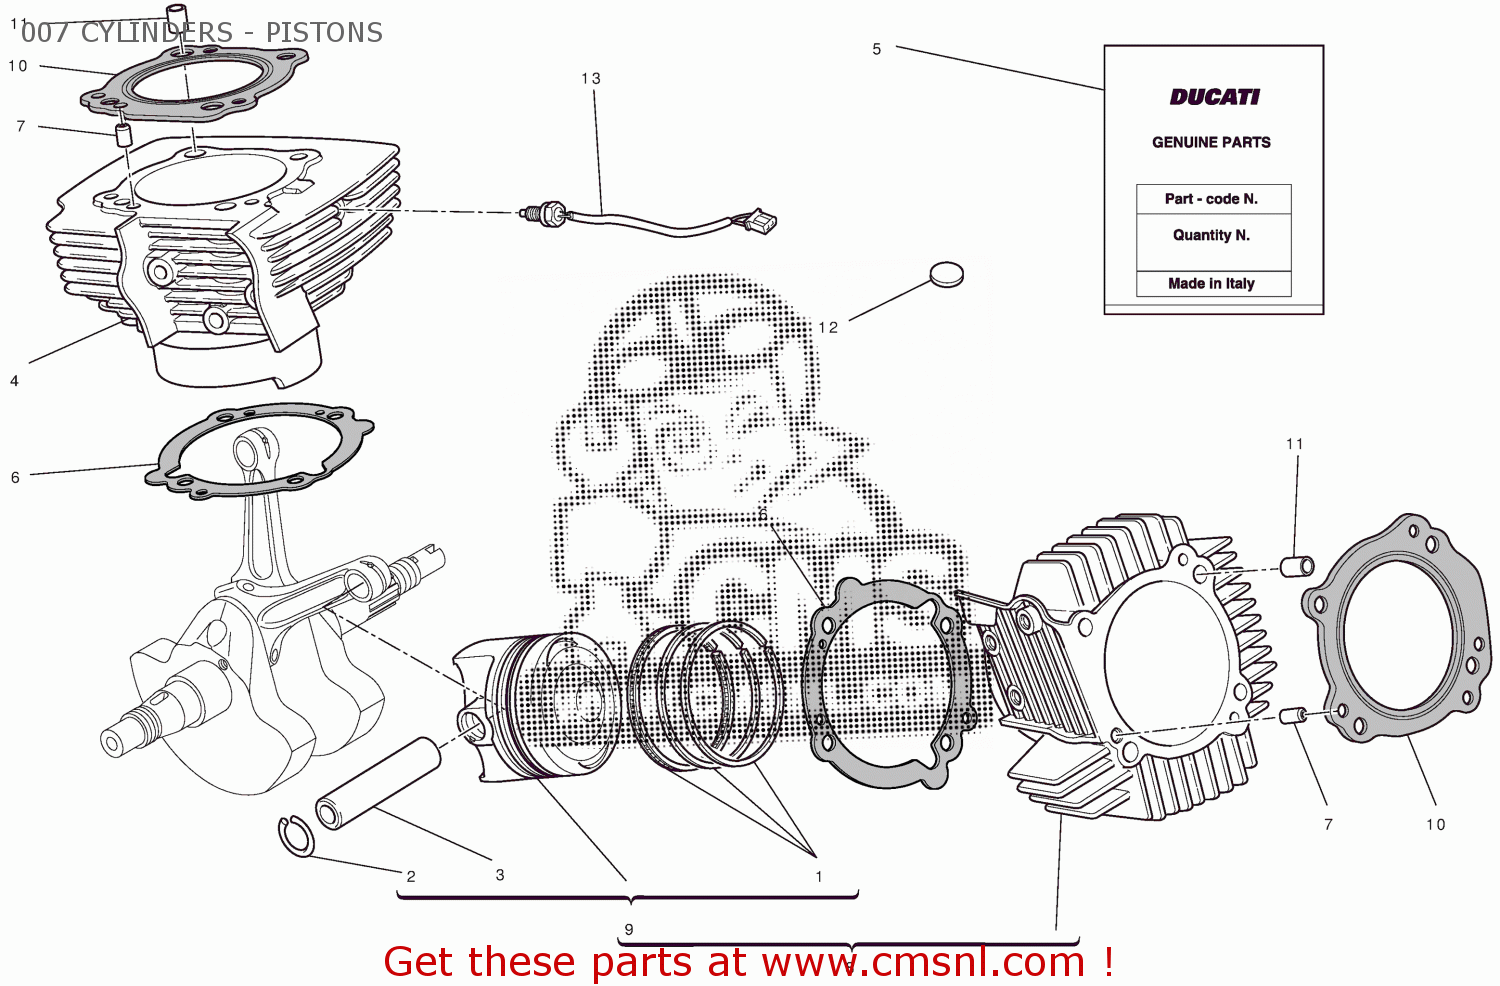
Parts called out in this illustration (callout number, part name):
1	PISTON RING SET
2	CIRCLIP, PISTON PIN
3	PISTON PIN
4	VERTICAL CYLINDER-PISTON FIT
5	GASKETS SET
6	CYLINDER-CRANKCASE GASKET TH. 0.4
7	BUSH
8	HORIZONTAL CYLINDER-PISTON FIT
9	PISTON ASSY
10	GASKET, CYLINDER HEAD
11	BUSH
12	VIBRATION DAMPER PAD
13	SENSOR, TEMPERATURE
